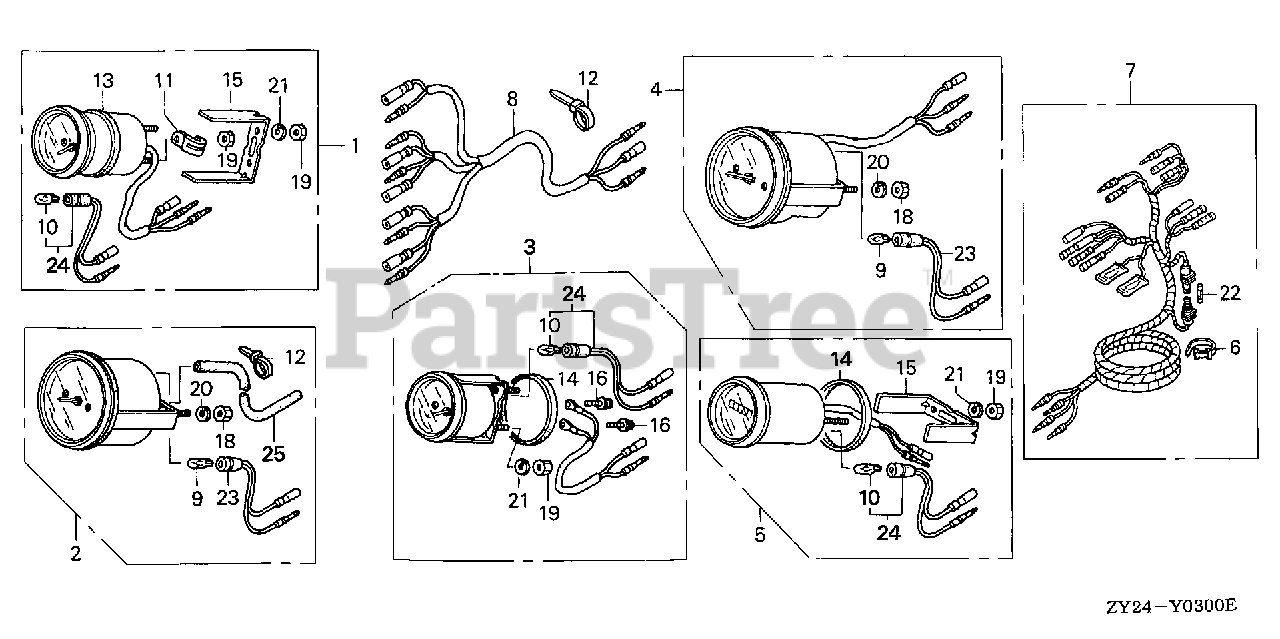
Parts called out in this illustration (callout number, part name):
1	METER KIT, TRIM
1	METER KIT, TRIM (B)
2	SPEEDOMETER KIT (NOT AVAILABLE)
2	SPEEDOMETER KIT (B) (NOT AVAILABLE)
3	METER KIT, VOLT
3	METER KIT, VOLT (B)
4	METER KIT, TACHO
4	METER KIT, TACHO (B)
5	METER KIT, HOUR (NA USE ALT:39700-ZW5-000ZA)
5	METER KIT, HOUR (B) (NA USE ALT:39700-ZW5-000ZA)
6	BAND B1, WIRE
7	HARNESS ASSY., METER (A)
8	HARNESS ASSY., METER (B)
9	BULB, WEDGE BASE (T10) (12V 1.7W) (STANLEY)
10	BULB, WEDGE BASE (12V 1.7W)
11	CLAMP
12	BAND, SELF-LOCK
13	GASKET
14	GASKET
15	BRACKET
16	SCREW-WASHER (3X22)
18	NUT, HEX. (5MM)
19	NUT, HEX. (4MM)
20	WASHER, SPRING (5MM)
21	WASHER, SPRING (4MM)
22	FUSE A (10A)
23	SOCKET
24	SOCKET
25	TUBE, SPEED METER (4X7X8000)
